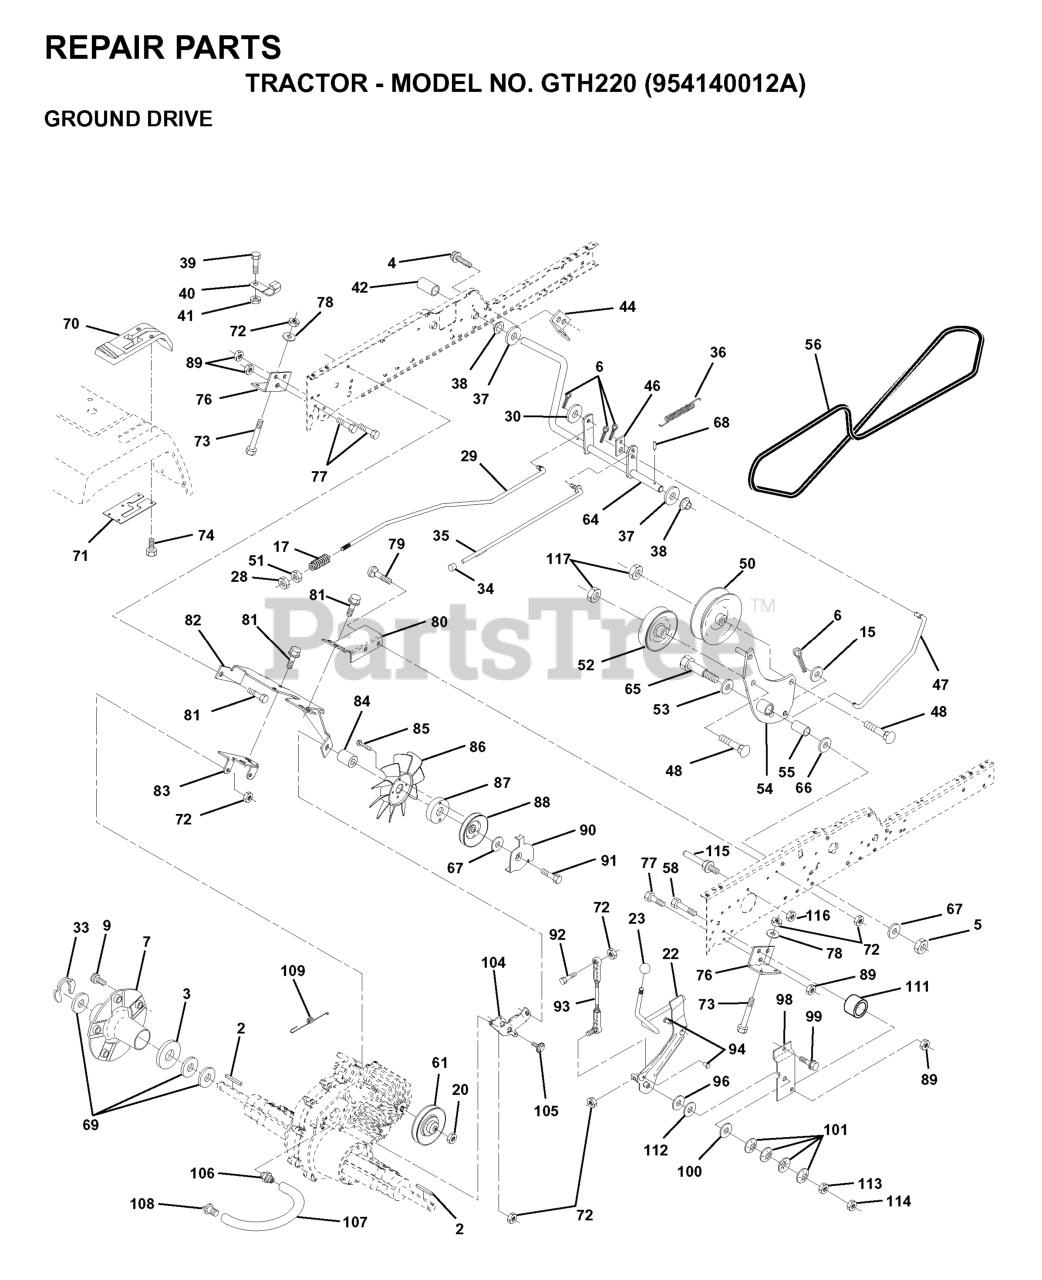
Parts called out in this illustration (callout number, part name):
2	KEY 1/4 X 2.5
6	COTTER PIN
7	HUB ASMBLY
15	WASHER
17	SPRING.ROD.BRAKE
20	NUT.HEX.1/2-20
22	SHAFT ARM ASMBLY
23	KNOB.DELUXE.(PISTOL.GRIP).BLAC
28	NUT
30	WASHER
33	E RING HYT
34	PLUNGER CAP
35	PARKING BRAKE ROD
36	SPRING DRIVE GROUND
39	Screw, Fin. #10-24 x 1
40	ACT-SWITCH T
41	LOCKNUT
42	COVER, PEDAL (1 2)
43	BOLT.HEX.1/4.X.3/4.DICHROMATE
44	BRKT SWITCH GT
45	LOCKNUT.NYLOC.1/4-20
46	RETAINER SPRING
47	CLUTCH ROD
49	Washer 13/32 x 7/8 x 13 Gauge
50	FLAT IDLER PULLEY
51	NUT
52	PULLEY.IDLER.V.
54	CLUTCH ARM ASSY
55	BEARING LT (2 2)
58	BOLT.HEX.7/16-14.FINISHED
64	SHAFT CLUTCH/BRAKE PEDAL
66	WASHER.BLADE
67	WASHER
68	ROLL PIN STD
70	CONSOLE, SHIFT HYD
71	PLATE CONSOLE SHIFT
72	NUT.71038.31-18.HEX.NYLOCK
73	Bolt Fin Hex 5/16-18 x 3
74	SCREW.HI-LO.CONSOLE
75	Nut, Lock Hex 7/16 Unc
76	BRACKET TRANSAXLE
77	BOLT
79	BOLT.CARR.5/16-18X5/8.SHORT
80	TORQUE BRACKET RH
81	SCREW
82	BRACKET MOUNT TORQUE/FAN
83	STRAP TORQUE MID
85	Screw #10-24 x 1-1/4
86	FAN 7" HYDRO
87	ADAPTOR.FAN.TRANSAXLE.VGTH
88	IDLER PULLEY
89	Nut, Crownlock Hex 7/16-14 unc
90	KEEPER.BELT
91	SCREW.HXWSH.3/8
92	BOLT
93	LINK ASM SHIFT
94	FASTENER.XMAS.TREE
98	SHIFT BRACKET
99	SCREW LT
103	JAM NUT TI
104	BRACKET IDLER
105	SCREW CRT
106	O-RING KIT 70110
107	LINE.VENT.HYDRO-GEAR
108	CAP, VENT ASSY
109	RETURN SPRING
115	KEEPER,DRIVE BELT
116	NUT LOCK HEX FLANGE 5/16-18
